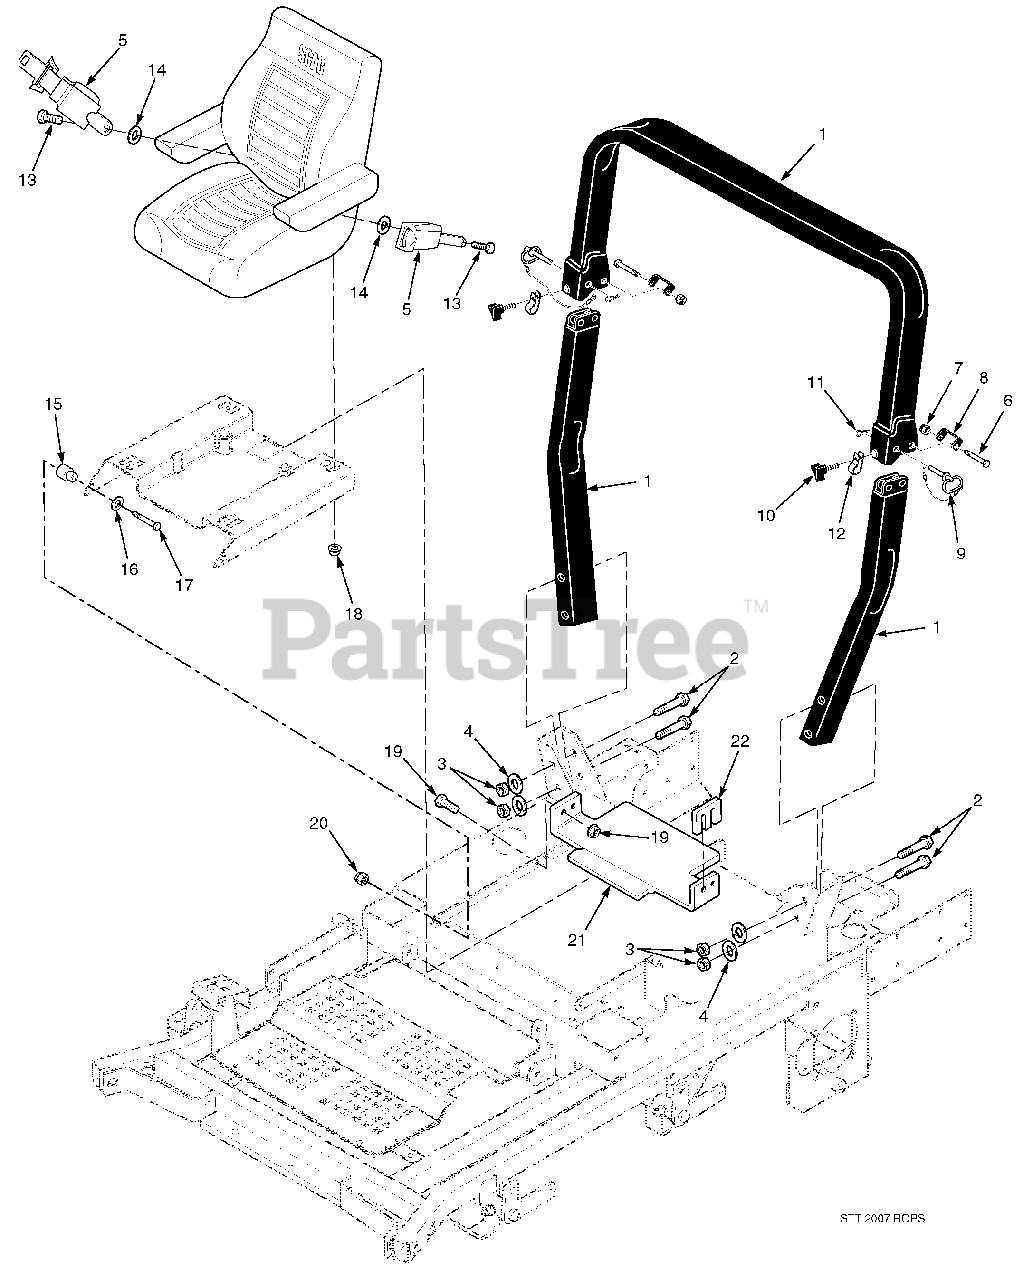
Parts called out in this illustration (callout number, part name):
1	STT, ROPS Acessory
2	Bolt, Hex Head 1/2-13 x 4-1/2"
3	Nut, Center Lock 1/2-13
4	Flatwasher, 1/2 (.562 x 1.375 x .109")
5	Retractable Seat Belt
6	Bolt, Hex Head 1/2-13 x 3-1/2"
7	Nut, Center Lock 1/2-13
8	Bracket, Stop
9	Pin
10	Thumb Screw, 5/16-18 NC x 3/4"
11	Hair Pin, Cotter
12	Clamp
13	Bolt, Hex Head 7/16-20 x 1"
14	Flatwasher, 7/16 (.500 x 1.25 x .083")
15	Sleeve, Seat Base Mounting
16	Flatwasher, 3/8 (.391 x .938 x .105")
17	Bolt, Hex Head 3/8-16 x 2"
18	Nut, Serrated Flange 5/16-18
19	Bolt, Hex Head 5/16-18 x 1"
20	Nut, Elastic Stop 3/8-16
21	Bracket, Seat Hold Down w/Decal
22	Spacer, Seat Hold Down
